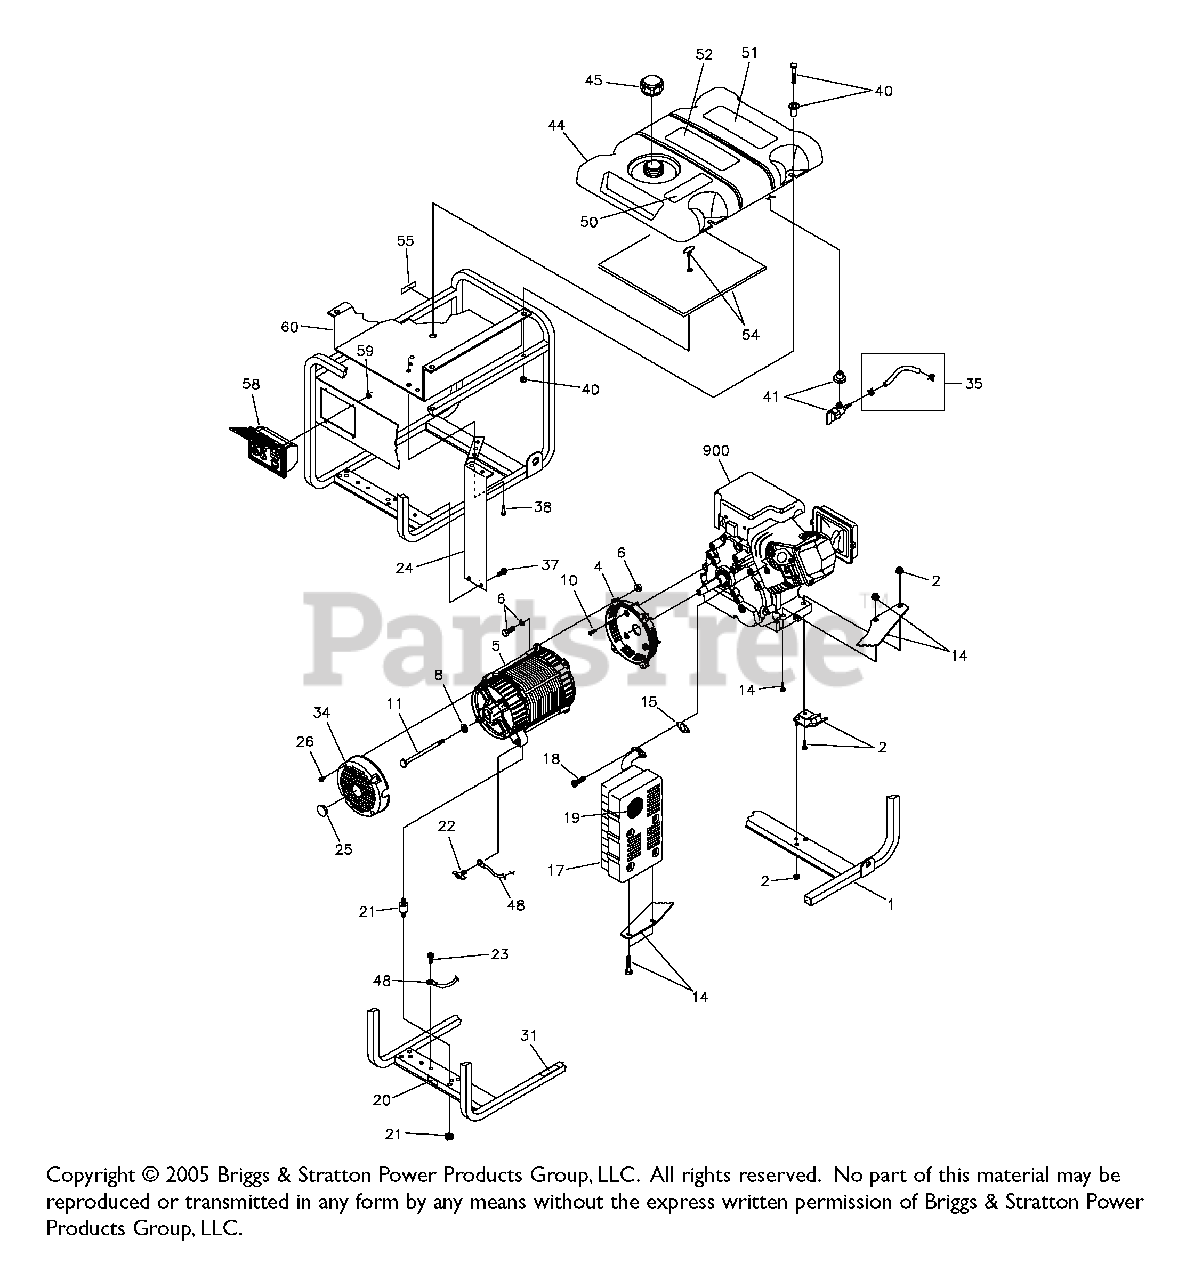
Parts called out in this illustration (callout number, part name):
2	KIT,Vibration Mount 45°.
4	HOUSING, Engine Adapter
5	ASSY,Alternator
6	KIT, Hardware Mounting Adapter
8	WASHER, M8 Flat
10	SBHCS, 3/8-16 x 1.0 Lg.
11	HHCS, 5/16-24 x 7-7/16
14	KIT, Muffler Bracket w/ Hardware
15	GASKET, Exhaust
18	SCREW, 5/16 - 18 x 3/4"
19	SCREEN, Spark Arrest
20	DECAL, Ground, Green
21	KIT,Vibration Mount
22	SCREW,Wing M6 1.0 x 16
23	SCREW, 10-16 x 3/4 Self Drill
24	SHIELD, Heat
26	SCREW, M5-0.8 x 10,Taptite
31	DECAL, Hot Muffler
34	COVER, Bearing Carrier
35	KIT, Fuel Hose w/ Clamps
37	SCREW, 12-14 x 7/8 Self Drilling
38	SCREW, 10-24 x 1/2 Crimptite
40	KIT, Fuel Tank Hardware
41	KIT,Valve,Tank
44	ASSY,Tank, Fuel
45	CAP, Fuel Gauge
48	WIRE, Ground
50	DECAL, Gas Fill
51	DECAL, Danger
52	DECAL, Start Instructions
54	KIT, Insulation w/ Clip
55	DECAL, Fuel Shut-off
58	ASSY, Control Panel
60	SHIELD, Heat
900	ENGINE
